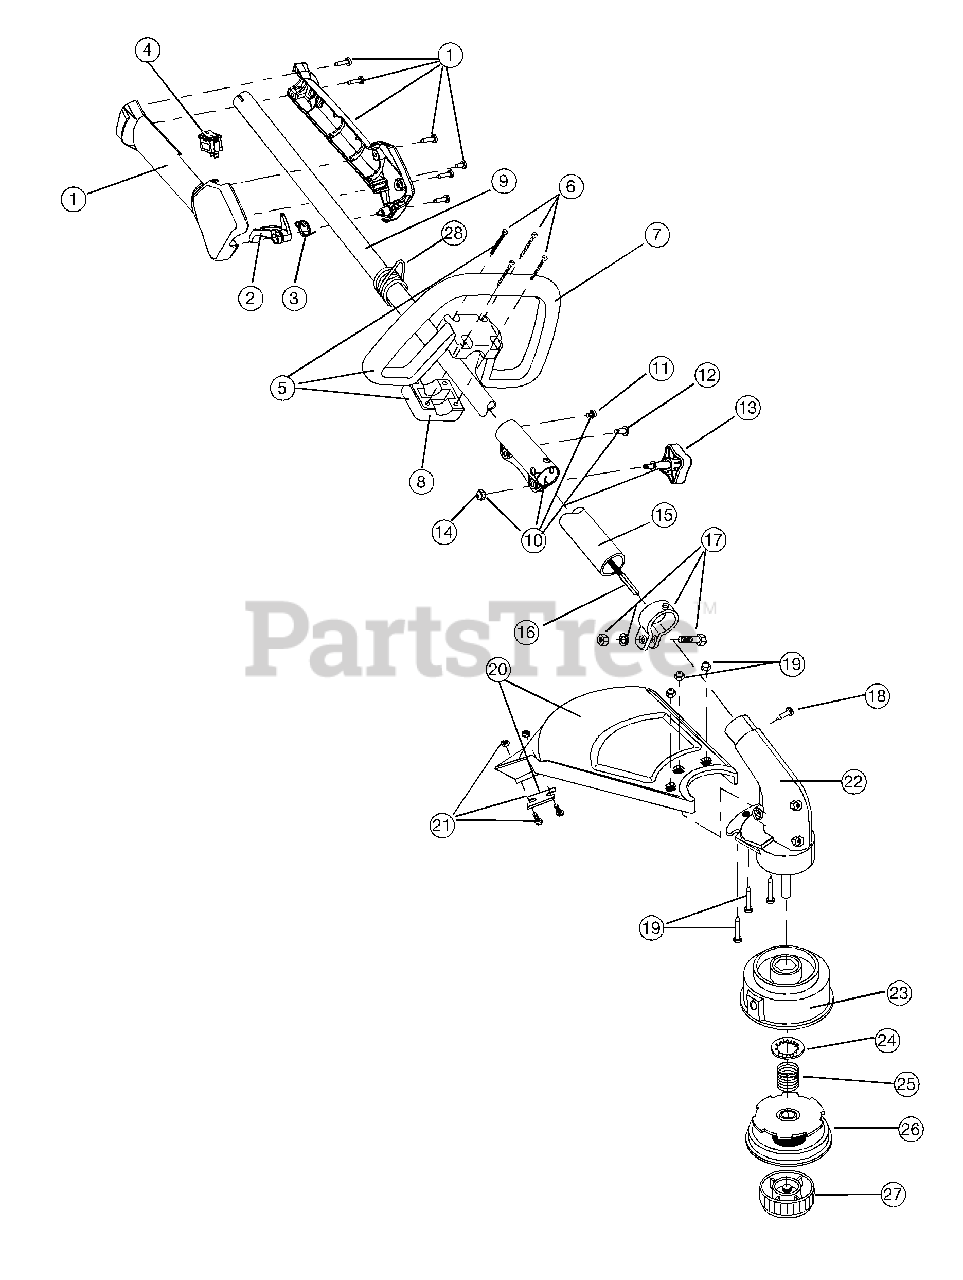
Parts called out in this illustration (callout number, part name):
1	Throttle Housing and Trigger Assembly (includes 2 & 3)
2	Throttle Trigger
3	Throttle Trigger Spring
4	Switch Assembly
5	Deluxe D-Handle Assembly (includes 6-8)
7	Deluxe D-Handle
8	Bottom Clamp
9	Upper Drive Shaft Housing Assembly
10	EZ-Link (TM) Coupler (includes 11-14)
13	Adjustment Knob
14	Knob Retaining Nut
15	Lower Drive Shaft Housing Assembly
16	Lower Flexible Drive Shaft
17	Lower Clamp Assembly (includes 18)
18	Anti-Rotation Screw
19	Shield Mounting Hardware
20	Shield and Blade Assembly (includes 21)
21	Blade Assembly
22	Gearbox Assembly
23	Outer Spool & Eyelet Assembly
24	Retaining Ring
26	Inner Reel
27	Bumb Head Knob Assembly
28	Harness Clip
